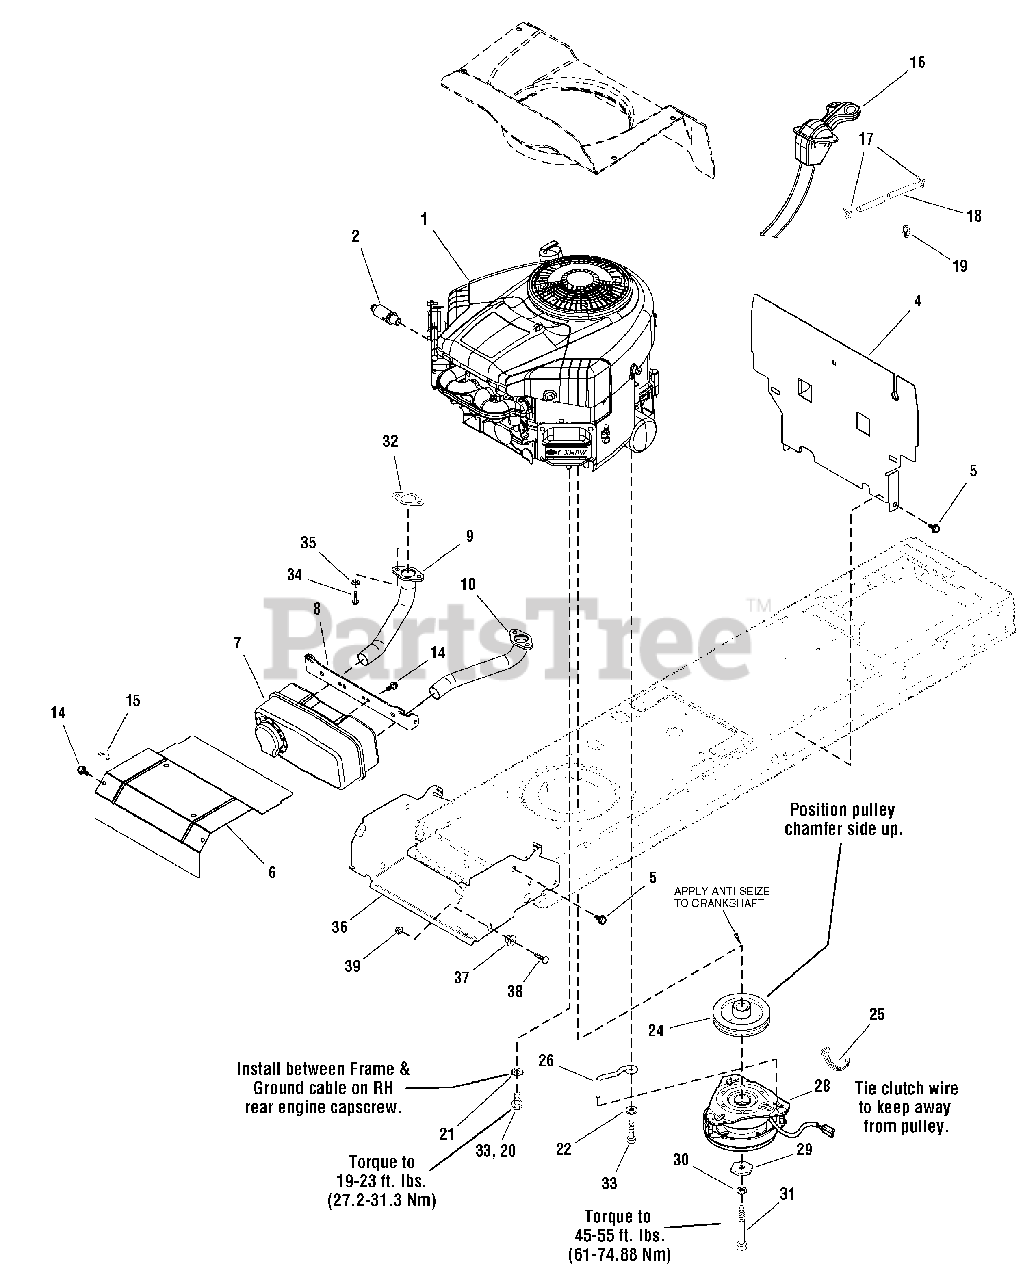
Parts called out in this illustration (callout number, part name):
1	* ENGINE, 23HP B&S Twin, Mod. 44L777-0128-B1
2	VALVE, Shut Off Oil Drain
4	SHIELD, Heat
5	SCREW, Hex Washer Head Taptite 5/16-18 x 5/8
6	SHIELD, Heat
7	MUFFLER
8	BRACKET, Muffler Mount
9	PIPE, Exhaust R.H.
10	PIPE, Exhaust L.H.
14	SCREW, Hex Washer Head Taptite 1/4-20 x 1/2
15	CLIP, Speed Wire
16	CONTROL, Throttle (Choke a Matic)
17	CLAMP, Hose
18	HOSE, Fuel
19	CLIP, Hose
20	SCREW, Hex Washer Head Taptite 3/8-16 x 1
21	LOCKWASHER, External Tooth 3/8
22	WASHER, 3/8
24	PULLEY & HUB ASSEMBLY, Engine
25	TIE, Self Locking
26	RETAINER, Clutch
28	CLUTCH, Electric OGURA
29	WASHER, Hex
30	LOCKWASHER, Spring
31	CAPSCREW, Hex Head 7/16-20 x 3-1/2 G5
32	GASKET, Exhaust
33	SCREW, Hex Washer Head Taptite 3/8-16 x 1-1/4
34	CAPSCREW, Hex Socket Head 5/16-18 x 3/4 G8
35	LOCKWASHER, Spring, 5/16
36	SUPPORT, Muffler
37	PIVOT, Hood
38	BOLT, Carriage, Short Neck, 5/16-18 x 1
39	NUT, Hex Flange, 5/16-18
